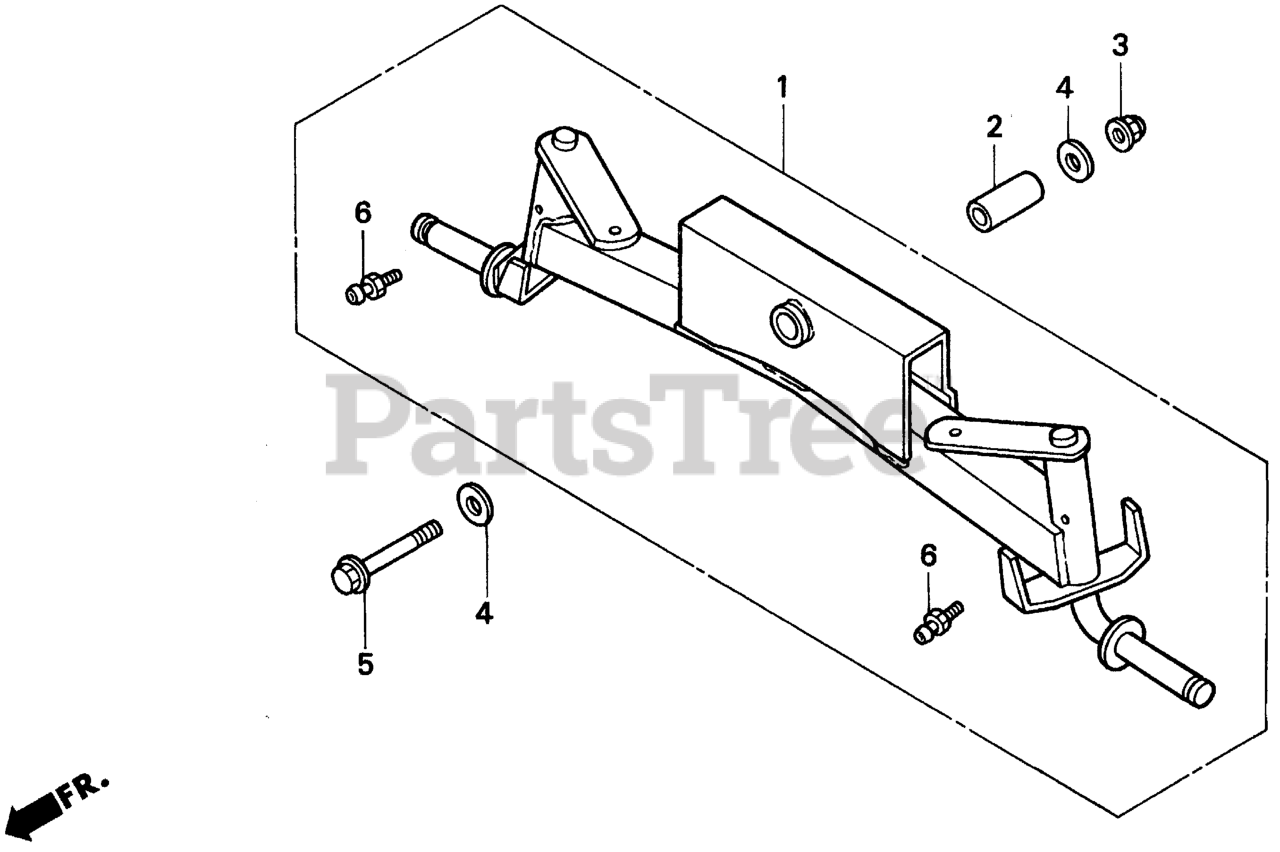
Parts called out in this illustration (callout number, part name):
2	COLLAR, FR. AXLE
3	NUT, SELF-LOCK (12MM) (SATO RASHI)
4	WASHER, SPECIAL (12MM)
5	BOLT, FLANGE (12X85)
6	NIPPLE, GREASE (A.T6) (M6X1.0)
